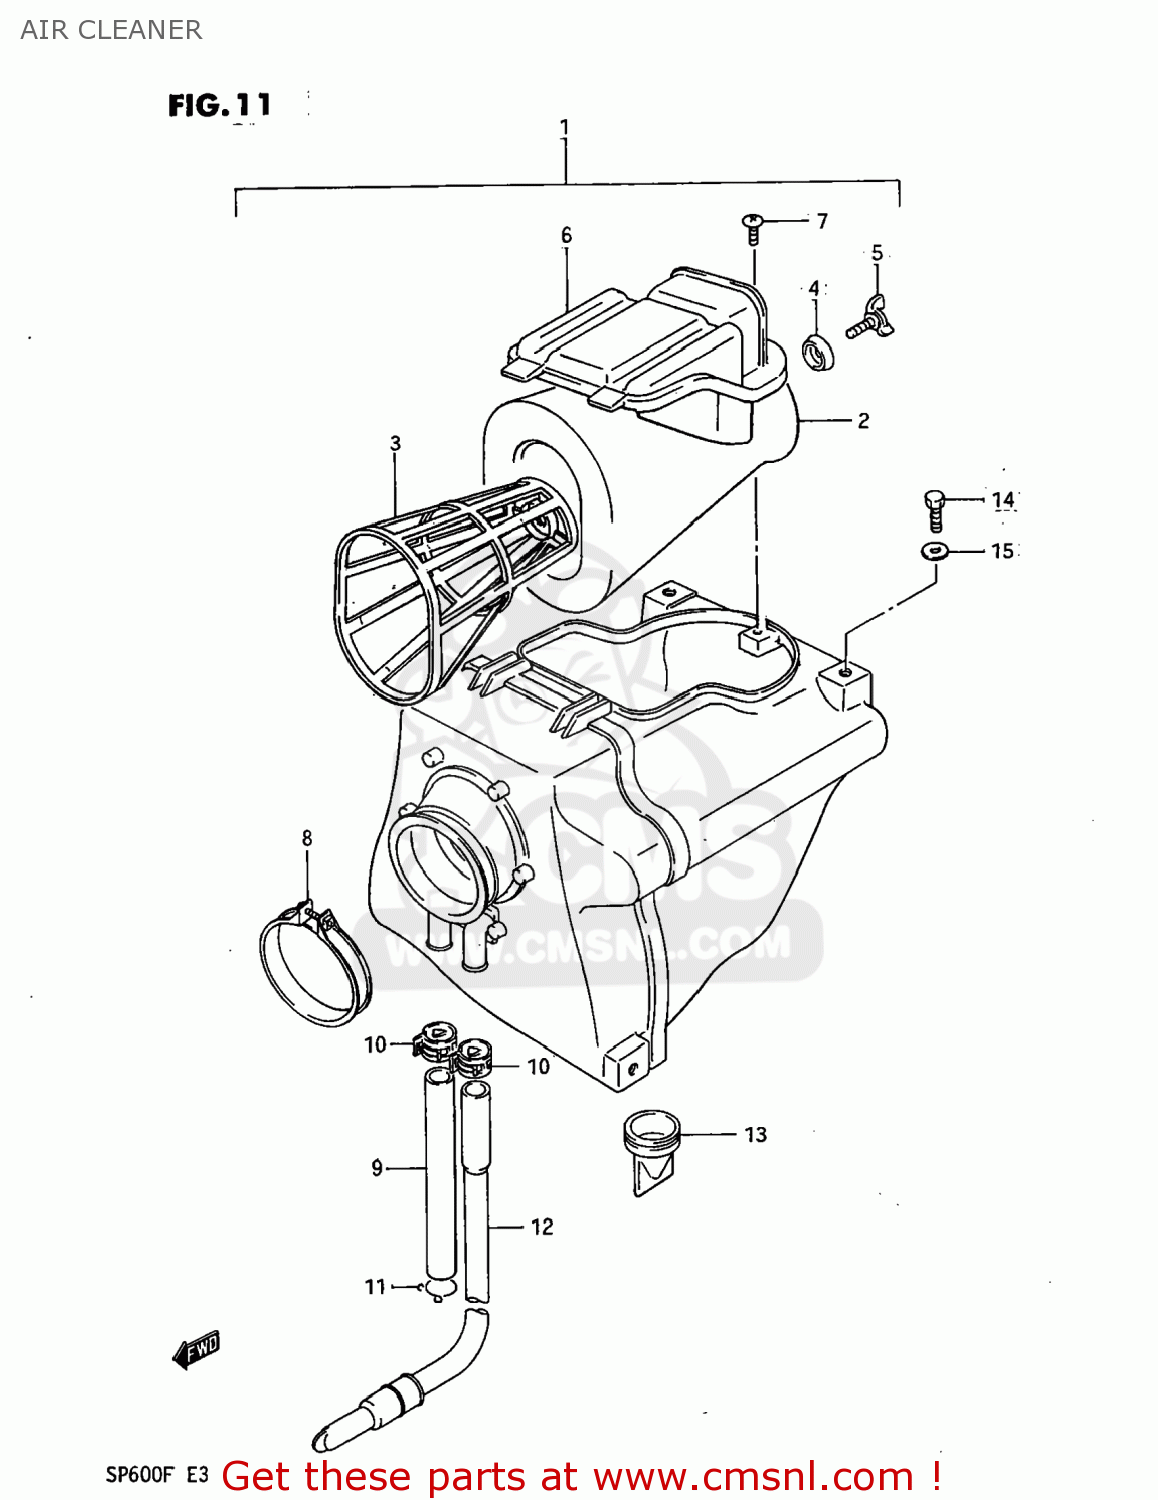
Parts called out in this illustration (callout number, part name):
1	CLEANER ASSEMBLY,AIR
2	FILTER,AIR CLEANER
3	HOLDER
4	WASHER,FILTER HOLDER
5	BOLT,AIR CLEANER
6	CAP,AIR CLEANER
7	SCREW
8	CLAMP
9	TUBE,BREATHER
10	CLIP
11	CLIP
12	DRAIN TUBE
13	HOSE,AIR CLEANER DRAIN
14	BOLT
15	WASHER
